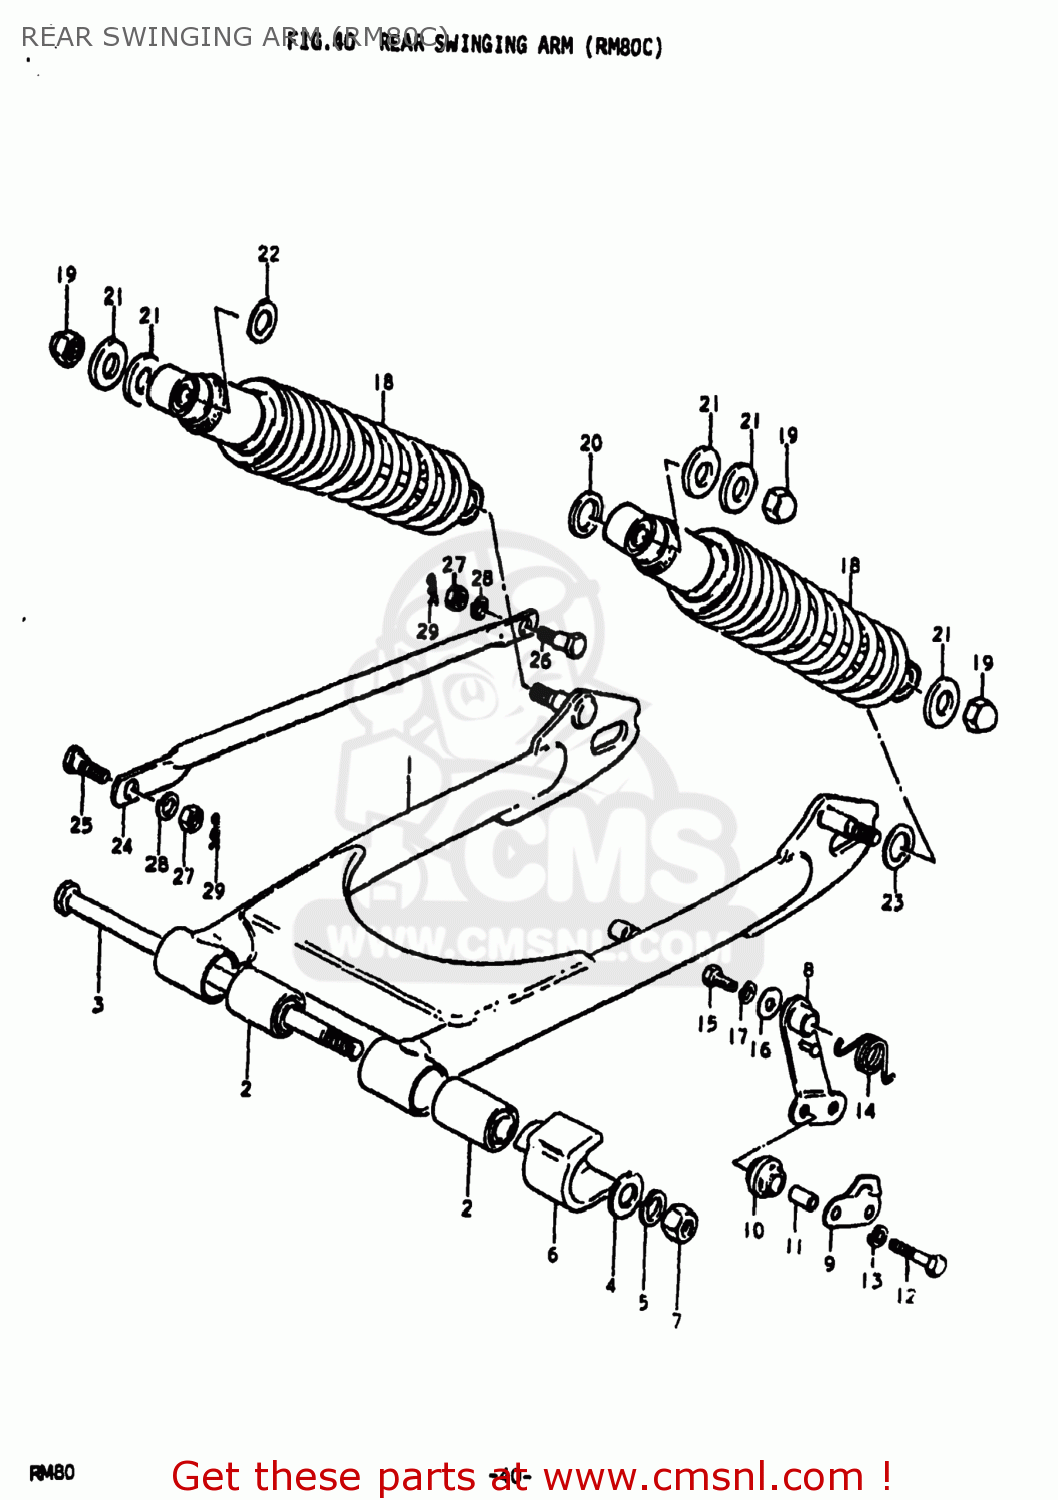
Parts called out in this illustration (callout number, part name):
1	SWING ARM ASSEMBLY,REAR
2	BUSH
3	SHAFT,REAR SWING ARM
4	WASHER
5	LOCK WASHER
6	BUFFER,CHAIN TOUCH DEFLECTOR
7	NUT
8	TENSIONER,CHAIN
9	PLATE,CHAIN TENSIONER
10	RUBBER,CHAIN GUARD
11	SPACER(6.5X10.5X22.5)
12	BOLT
13	LOCK WASHER
14	SPRING
15	BOLT
16	WASHER
17	LOCK WASHER
18	SPRING
19	NUT
20	WASHER
21	WASHER
22	WASHER (12.5X24X3.2)
23	WASHER(12.5X20X1)
24	TORQUE LINK,REAR
25	BOLT(8X22)
26	BOLT(8X26.5)
27	NUT
28	LOCK WASHER
29	CLIP
